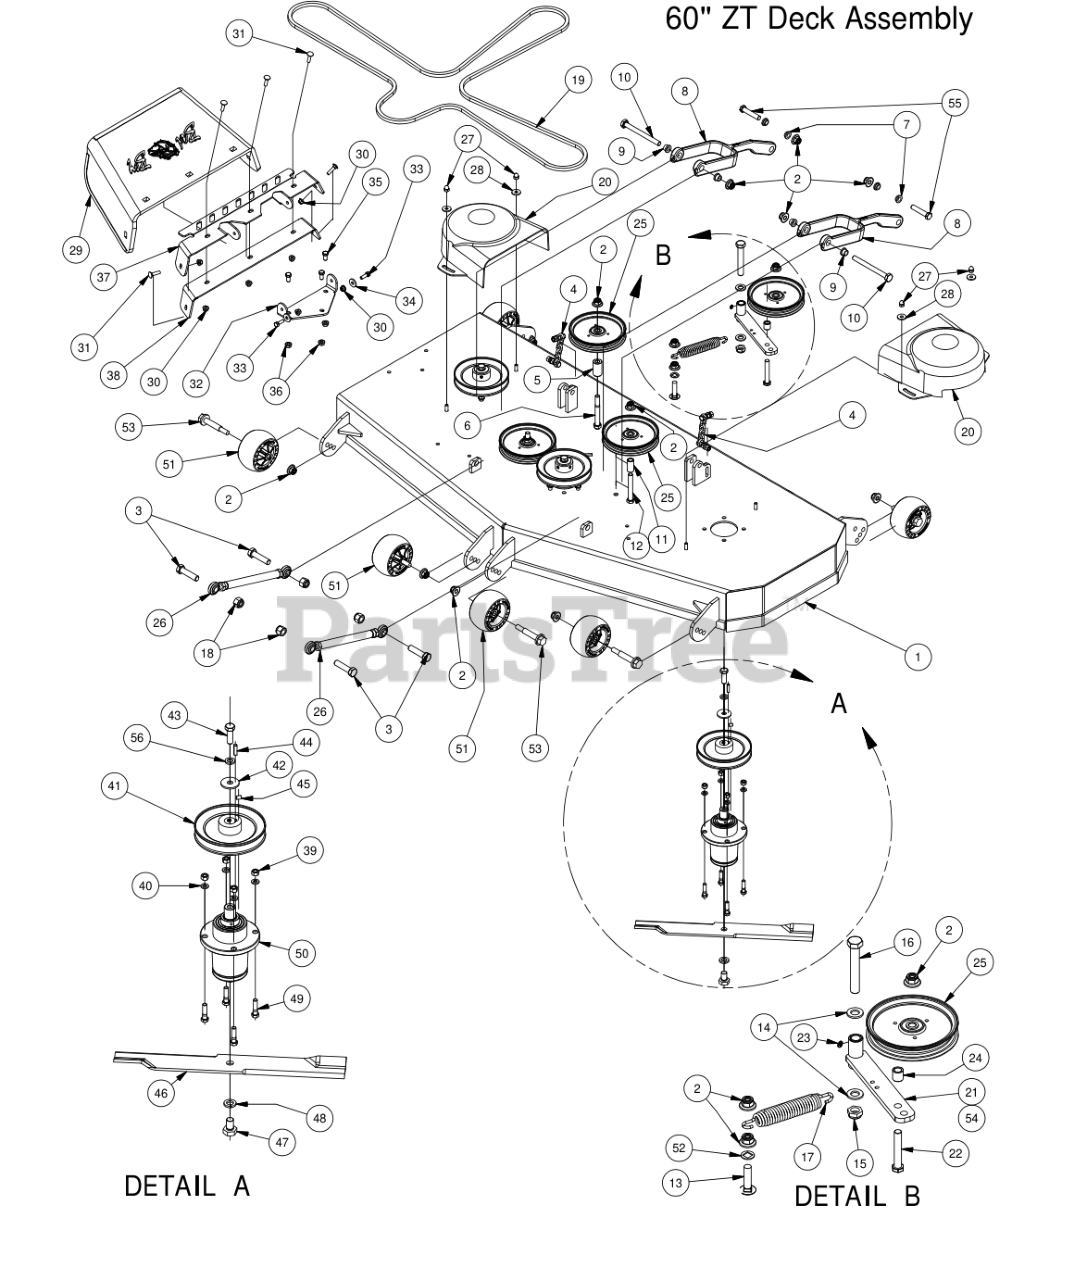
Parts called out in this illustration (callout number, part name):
1	60" ZT/Maverick Deck
2	1/2-13 Nylon Flange Nut
3	5/8" x 2 1/2" Grade 5 Hex Bolt (Coarse)
4	Chain assembly
5	1 3/4" Pulley Spacer
6	1/2" x 4" Bolt (Grade 8)
7	Flange Bushing For Lower Deck Arm
8	Deck Arm Assembly
9	Flange Bushing For Upper Deck Arm
10	1/2" x 5 1/2" Bolt
11	.502 ID X.750 OD X 1.500 Long Spacer
12	1/2 x 3 1/2 Flange Bolt Grade 8
13	1/2 x 2" Carriage Bolt
14	.630 ID Plastic Washer
15	5/8-11 Nylon Insert Jam Half Nut
16	5/8" x 4" Hex Bolt
17	2009 Deck/Pump Idler Spring
18	5/8 Std NC Nylock Nut
19	60" ZT Deck Belt
20	2014 ZT Pulley Cover
21	Deck Idler
22	1/2-13 x GR 5 Hex Bolt Zinc
23	1/4" Press in Grease Fitting
24	Spacer 3/4 OD x 1/2 ID x 3\4 Length
25	5-3/4 Idler Pulley
26	Turnbuckle (Top Link)
27	Acorn nut-pulley Cover
28	.360 ID Plastic Washer-Black
29	Rubber Discharge Chute
30	5/16" Nylon Flange Nut
31	5/16" x 1 1/4" Carriage Bolt
32	Discharge Chute Hanger (Deck Mounted)
33	5/16" x 1" Bolt
34	.360 ID Plastic Washer
35	3/8" x 3/4" Hex Bolt
36	3/8" Flange Nut
37	60" Discharge Chute Upper Hanger
38	60" Lower Hanger
39	3/8" Hex Nut
40	3/8" Lock Washer
41	6 1/4" Drive Pulley
42	1/2 Belleville Washer
43	1/2"-20 x 1 1/2 - Grade 5 Fine Thread Bolt
44	1/4" x 1" Key
45	5/16 Set Screw
46	60 Inch Fusion Blade
47	5/8" x 1 1/2" Grade 8 Hex Bolt (Fine)
48	5/8" Lock Washer
49	3/8" x 1 1/4" Hex Bolt
50	Spindle Assembly
51	Anti-Scalp Rollers
52	.517 Square Hole Round Washer
53	Deck Wheel Bolt
54	Deck Idler Assembly (Components 2,21,22,23,24,25)
55	1/2" x 3" Hex Bolt
56	1/2" Lock Washer
